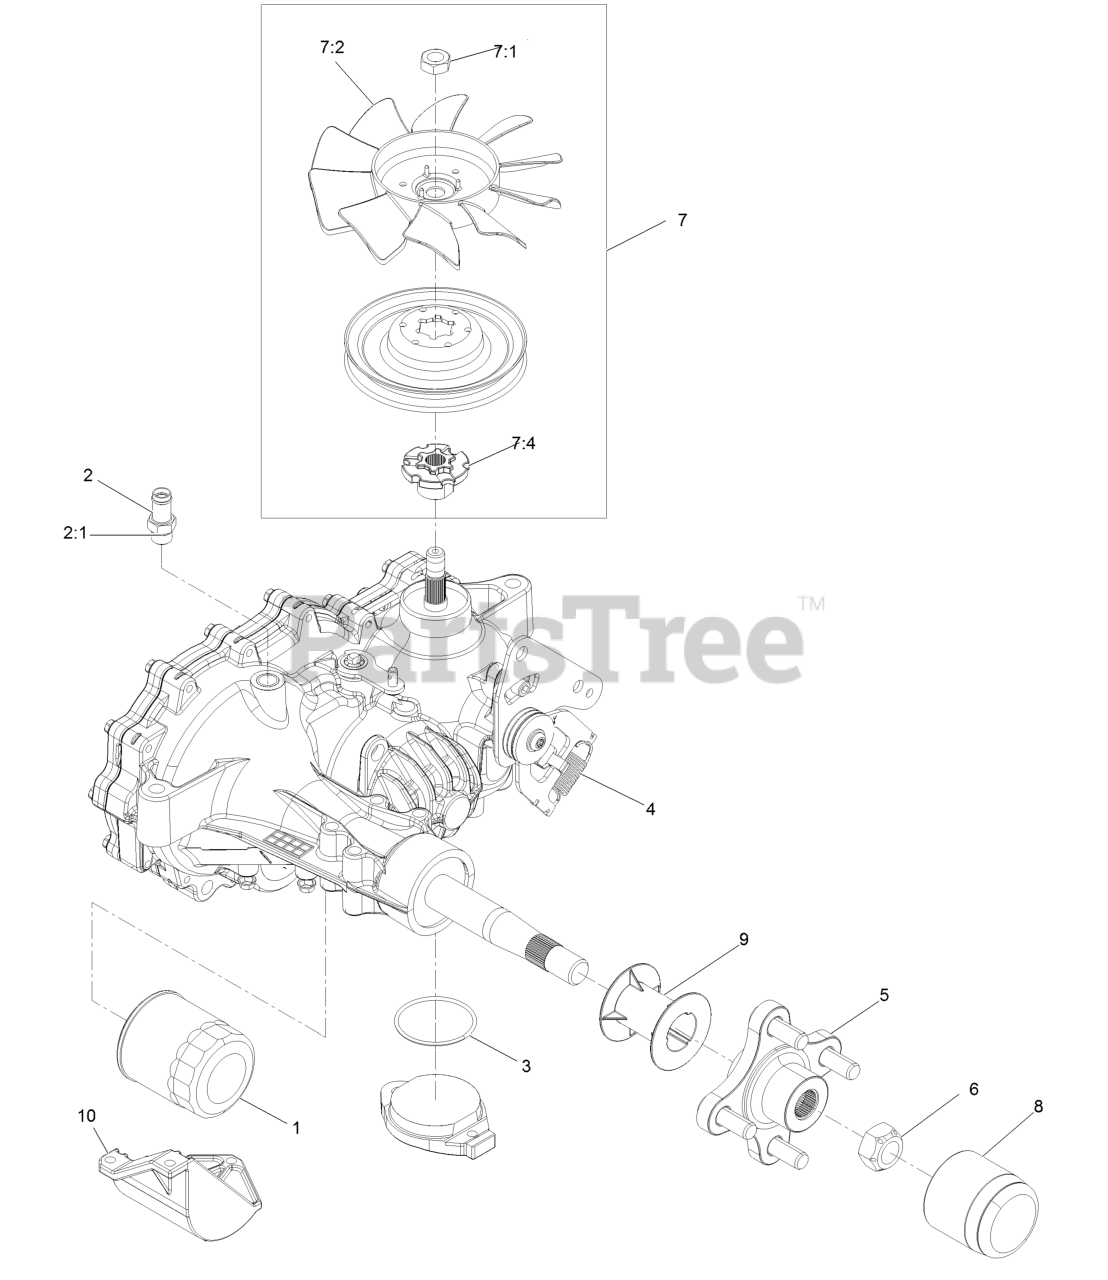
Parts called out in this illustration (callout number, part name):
1	Filter-Hydraulic
2	Adapter-Straight
2:1	O-Ring
3	O-Ring-Charge Seal Cover
5	Hub-Offset
6	Nut-Hub
7	Fan And Pulley Kit
7:4	Hub-Pulley
8	Cap-Axle, Long
9	Tube-Axle
10	Guard-Filter, RH
99	Seal Kit
